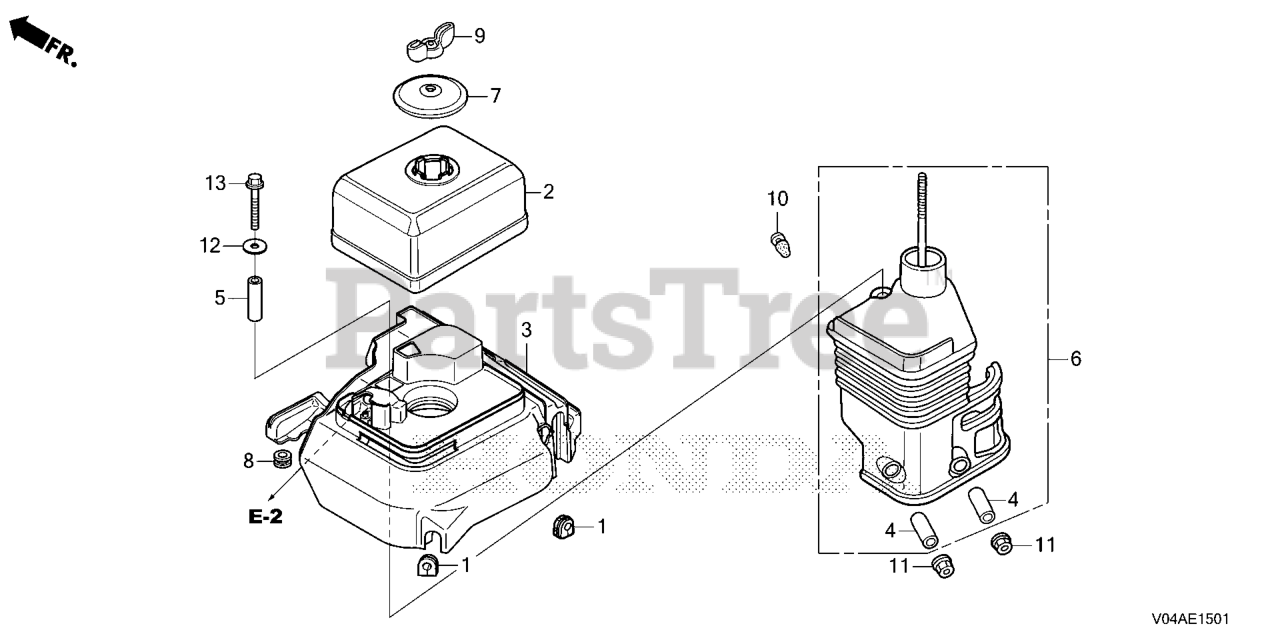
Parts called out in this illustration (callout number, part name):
1	GROMMET, OIL PIPE HOLDER
2	COVER, AIR CLEANER (SEMI-DRY)
3	NOSE, MUFFLER
4	COLLAR, AIR CLEANER Use from Engine SN 1786085.
5	COLLAR B, AIR CLEANER
6	ELBOW, AIR CLEANER
7	CAP, AIR CLEANER
8	RUBBER, SCREEN SETTING
9	WINGNUT, TOOL BOX SETTING
10	PLUG, CONE TYPE
11	NUT, FLANGE (6MM)
12	WASHER, PLAIN (6MM)
13	BOLT, FLANGE (6X45)
